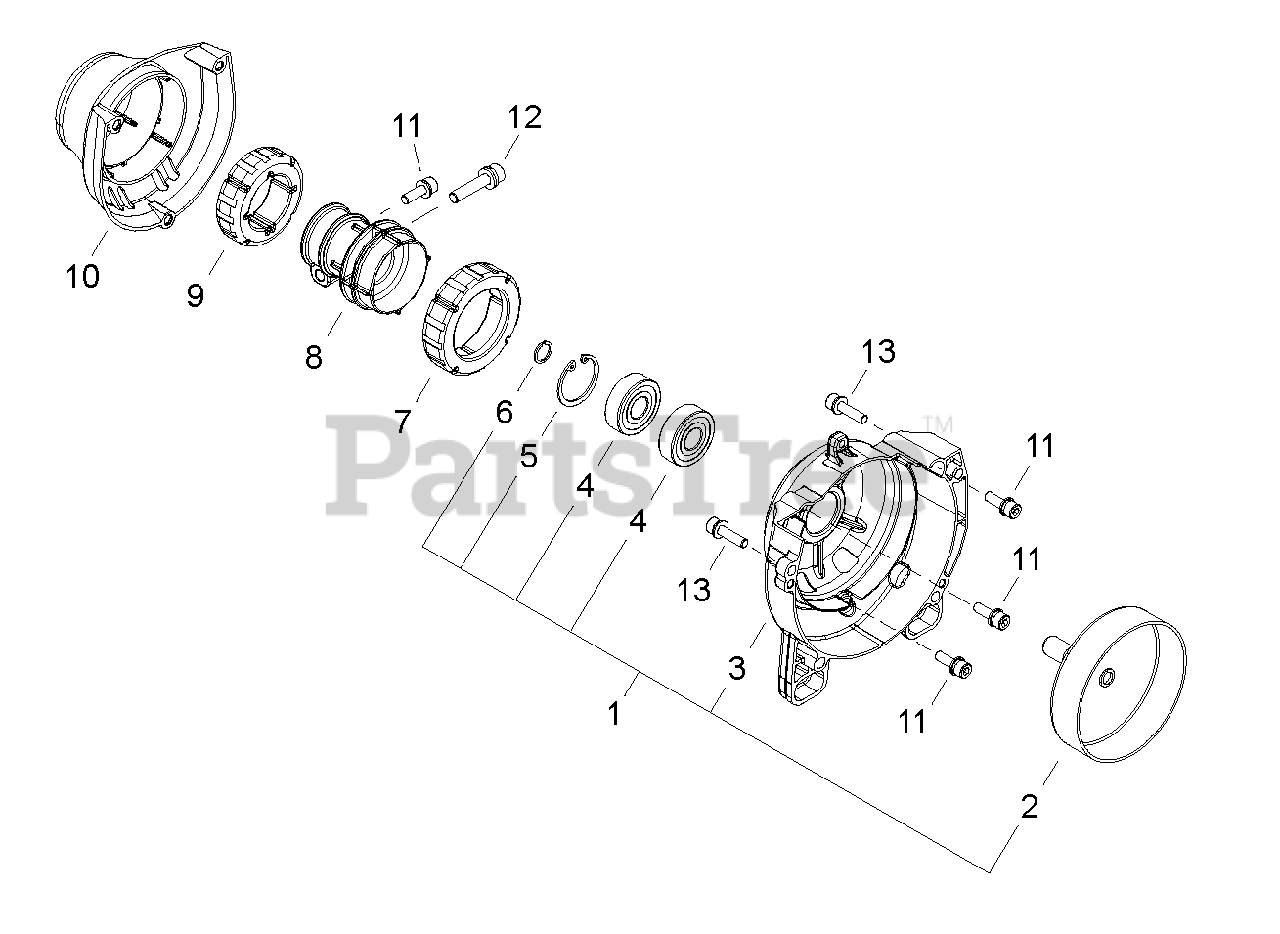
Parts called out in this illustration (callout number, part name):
1	FAN CASE ASSY
2	DRUM, CLUTCH
3	CASE, FAN
4	BEARING, BALL - 6001DDUC3
5	RING, RETAINING - 28
6	RING, RETAINING
7	CUSHION - REAR
8	CUSHION
9	CUSHION - FRONT
10	COVER, CUSHION
11	SCREW - 5X16
12	SCREW - 6X28
13	SCREW - 5X20
